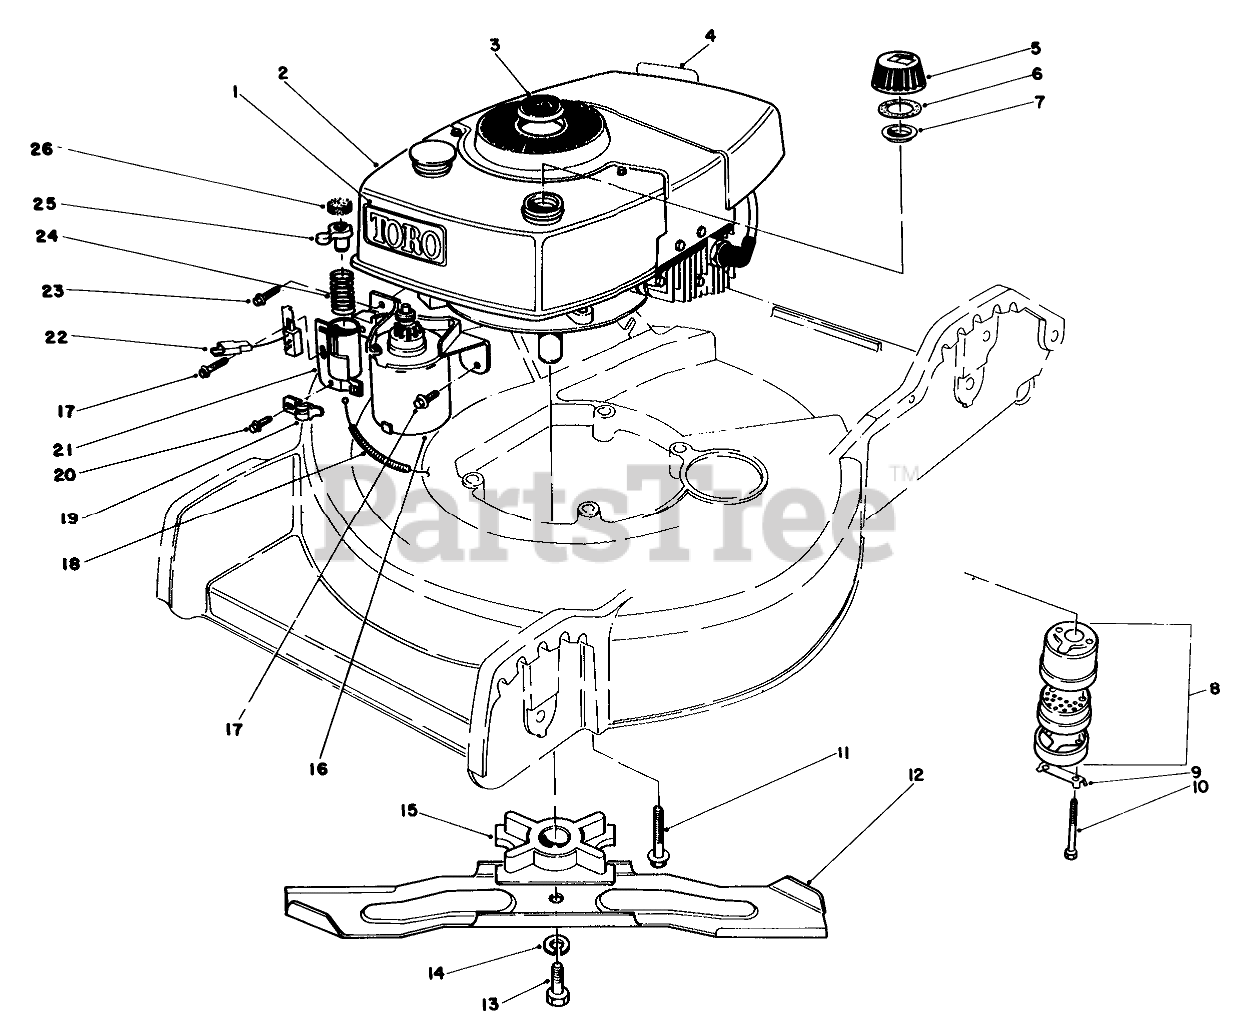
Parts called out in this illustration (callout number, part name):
1	Decal Tow
3	PLUG BUTTON
4	Decal-Maintenan
5	Gas Cap Assembly (Incl. Ref. #6 & 7)
6	GASKET
7	GAS CAP BAFFLE
8	Muffler Assembly (Incl. Ref. #9 & 10)
9	CLIP - LOCKING
10	SCREW-HH
11	3/8-16 X 2 CAPSCREW
12	Blade
13	SPECIAL SCREW
14	WASHER-LOCK
15	BLADE RETAINER
16	STARTER MOTOR ASM
17	SCREW
18	BRAKE CABLE-SUZUKI
19	CABLE CLAMP
20	SCREW
21	TUBE W A
22	PUSH BUTTON SWITCH
23	Screw
24	COMPRESSION SPRING
25	Plunger
26	Pad-Friction
